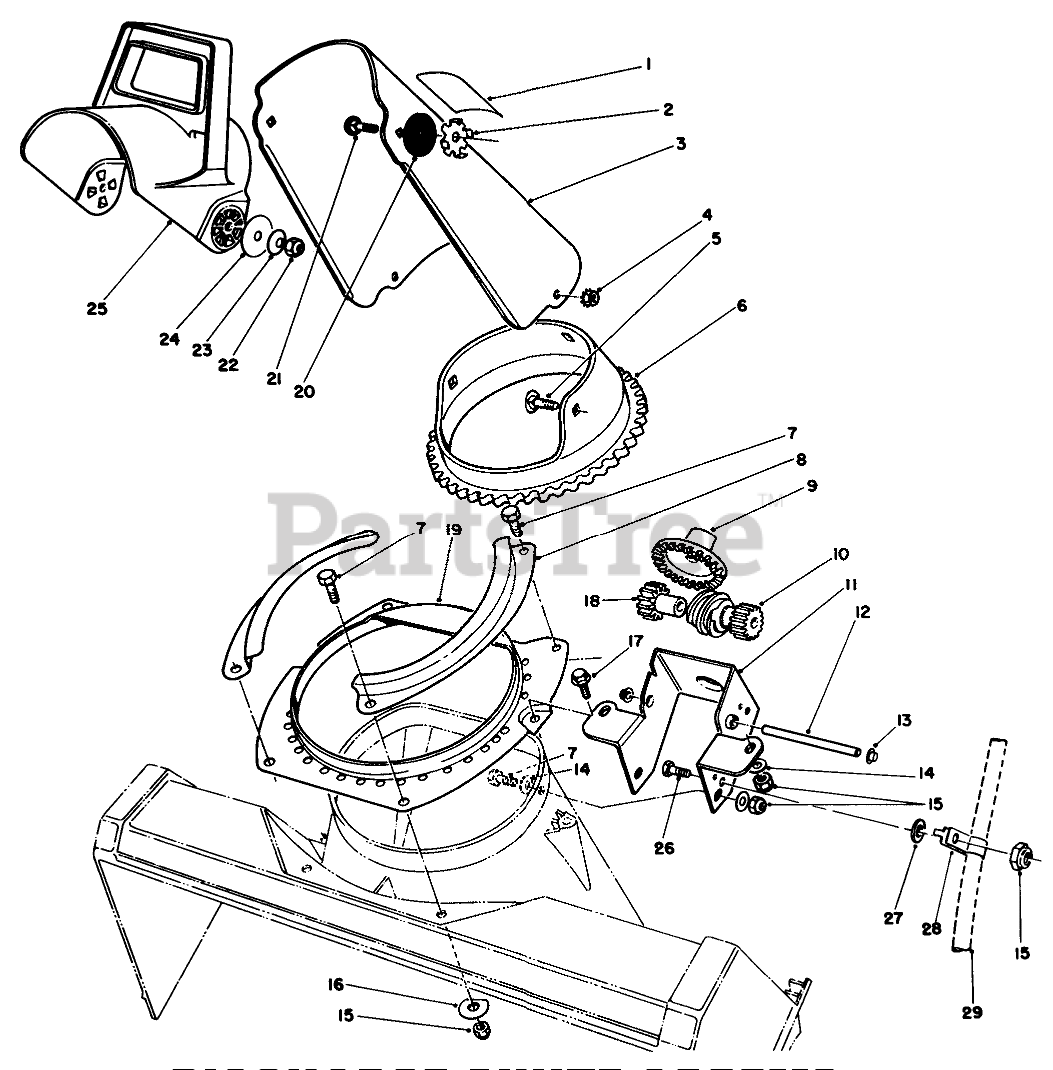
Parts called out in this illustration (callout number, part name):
1	Decal-Discharge
2	PLATE-FRICTION
3	Chute-Discharge (Incl. Ref. #1)
4	NUT-KEPS
5	SCREW-CARR
6	RING-GEAR, CHUTE
7	SCREW-HH
8	Retainer-Chute Ring
9	GEAR-FACE
10	GEAR-SPUR/WORM
11	Bracket-Chute Gears
12	SHAFT-GEAR, WORM
13	NUT-PUSH
14	WASHER-FLAT
15	NUT-LOCK, NI
16	Washer
17	SCREW-PLASTITE
18	GEAR-SPUR, SPACER
19	Ring-Chute Support
20	WASHER-RUBBER
21	SCREW-CARR
22	NUT-LOCK, NI
23	WASHER-BELLEVILLE
24	WASHER-FLAT
25	CHUTE-DEFLECTOR
26	SCREW-CARR
27	WASHER-PLAIN
28	ABLE CLAMP
29	CABLE COVER
